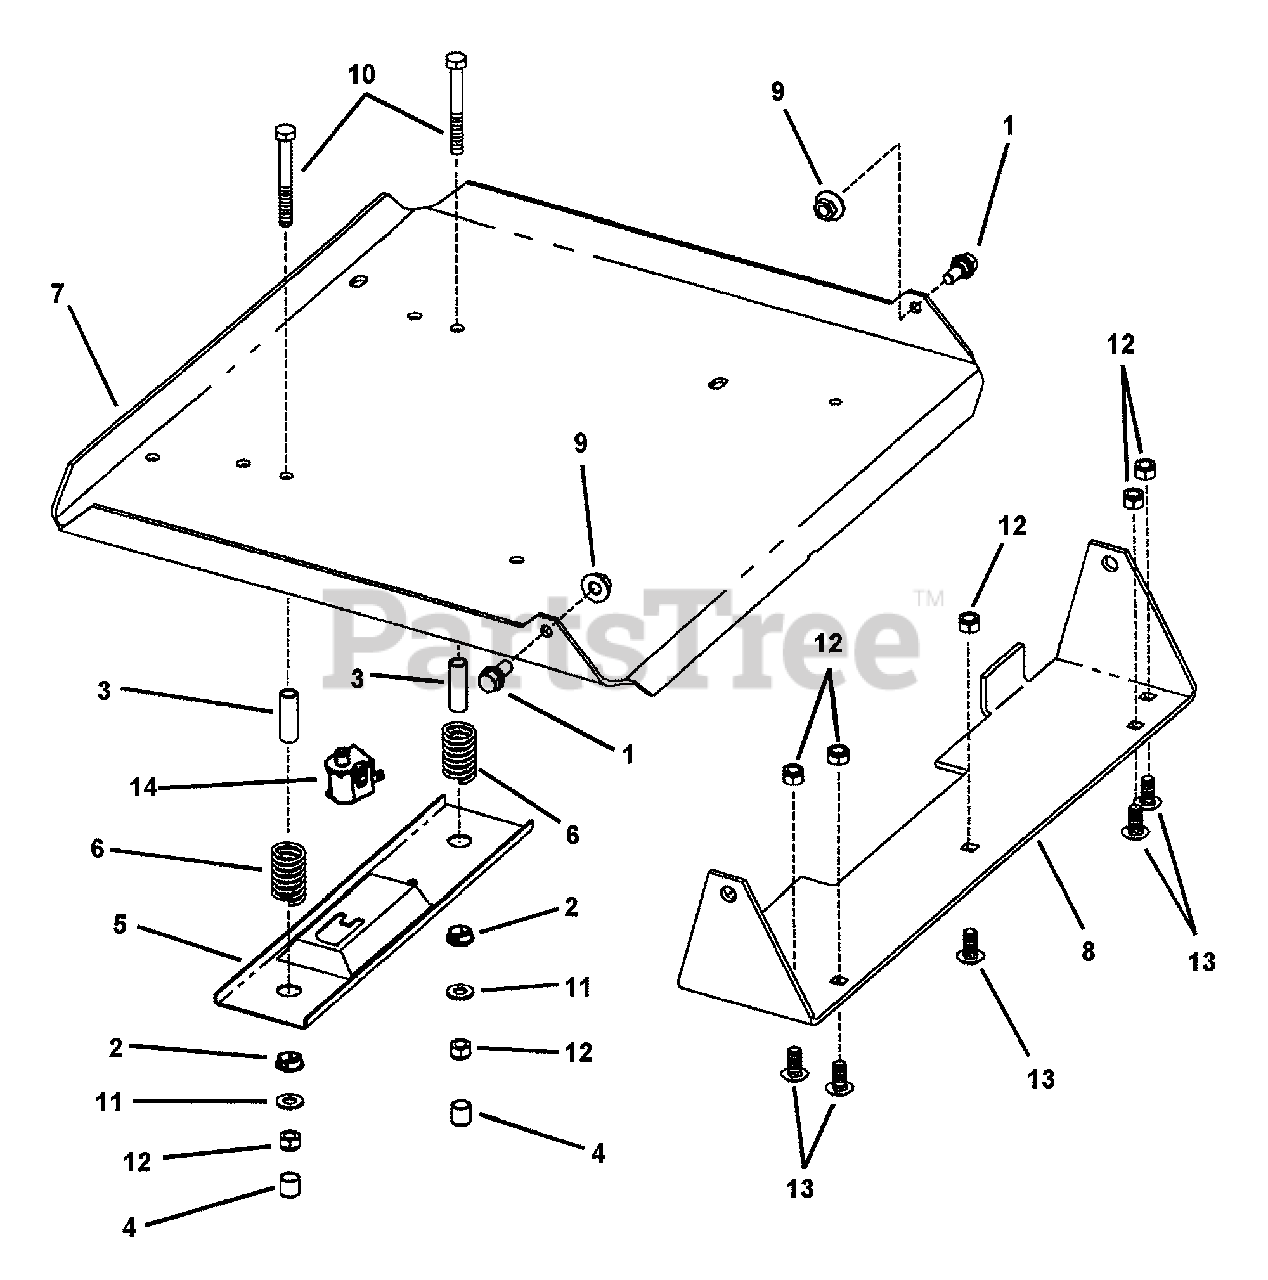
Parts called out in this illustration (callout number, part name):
1	BOLT, 5/16-18 Shoulder
2	BUSHING, Molded Seat, 1/2 I.D., 5/8" O.D.
3	SPACER, .31 I.D., 1-3/8" Long
4	CAP, Vinyl, 1/4 I.D. x 1/5 O.D.
5	HOLDER, Seat Switch
6	SPRING
7	PLATE, Seat Mount
8	BRACKET, Seat Hinge
9	NUT, 5/16-18 Hex Large Flange Center Lock
10	BOLT, 5/16-18 X 2-1/2" GD5 YZ
11	WASHER, 5/16" Flat
12	NUT, 5/16-18 HEX NYLON LOCK
13	BOLT, 5/16-18 x 3/4 Short Neck. Carriage, Grade 5
14	SWITCH, Seat
